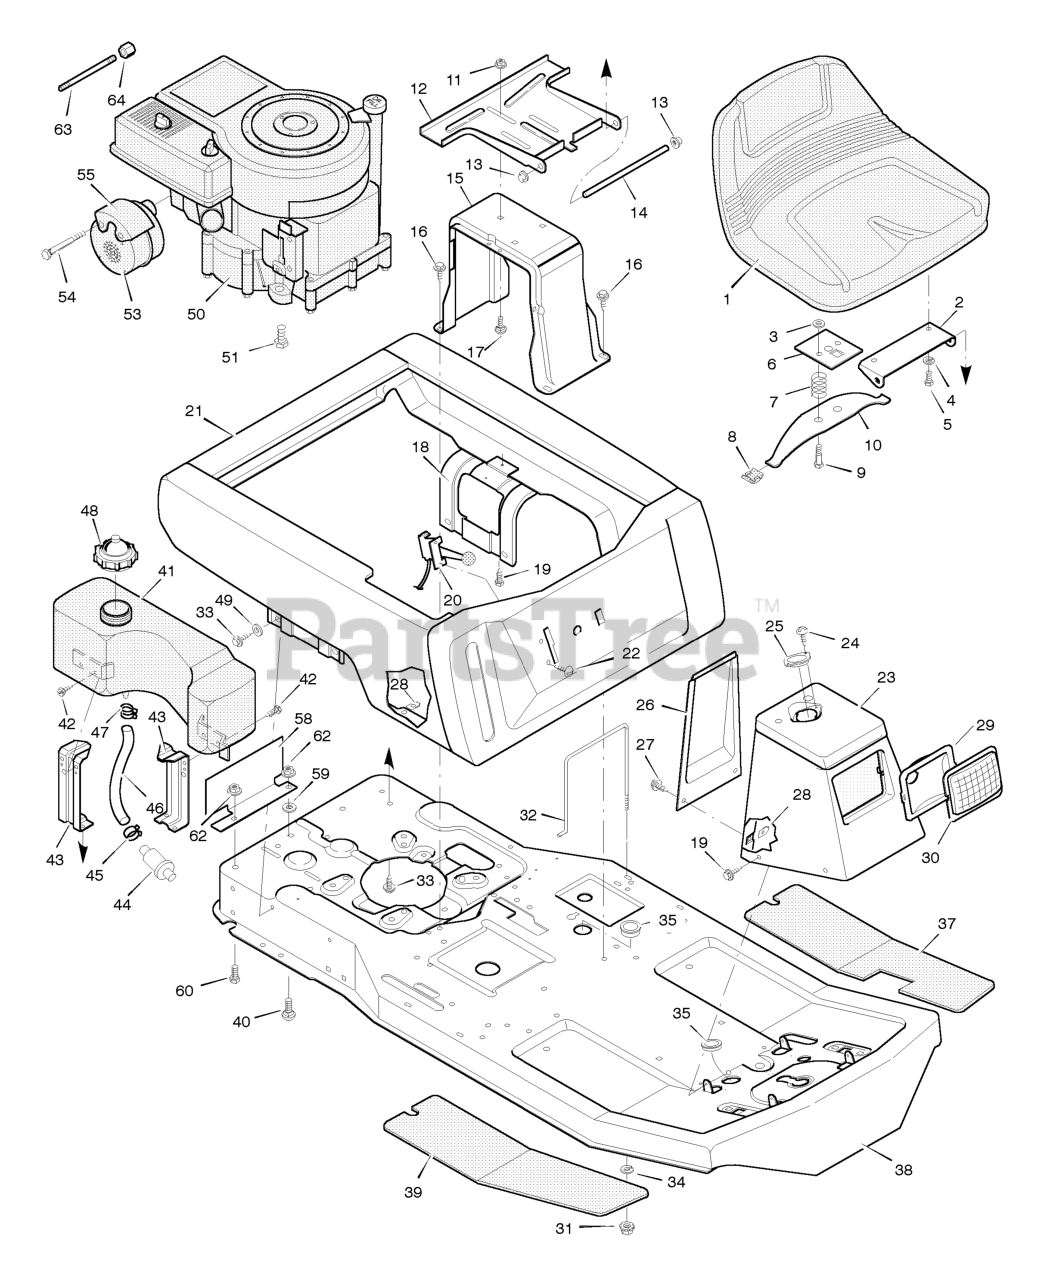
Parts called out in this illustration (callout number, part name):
2	Hinge, Seat
3	Retainer
4	Lockwasher
5	Bolt, Hex
6	Plate, Seat Switch
7	Spring, Compression
8	Glide, Seat Spring
9	Bolt, Shoulder
10	Spring, Seat
11	Locknut, Flange
12	Bracket, Seat Pivot
13	Cap, Push On
14	Rod, Seat Hinge
15	Support, Seat
17	Bolt, Carriage
18	Support, Body
20	Throttle Control
23	Console Assembly
25	Bearing, Steering Post
26	Console, Plate
28	J- Nut
29	Reflector
31	Locknut
32	Clamp, Battery
35	Grommet
37	Mat, Left
38	Frame Assembly
39	Mat, Right
40	Bolt, Carriage
41	Tank, Fuel
43	Bracket, Fuel Tank
44	Filter, Fuel
46	Line, Fuel
47	Clamp
48	Cap, Fuel
49	Washer
50	Engine *
51	Bolt, Engine Mount
53	Muffler
55	Shield, Heat
58	Shield, Heat
59	Washer
60	Bolt
62	Locknut, Flange
63	Pipe, Oil Drain
64	Cap, Oil Drain
